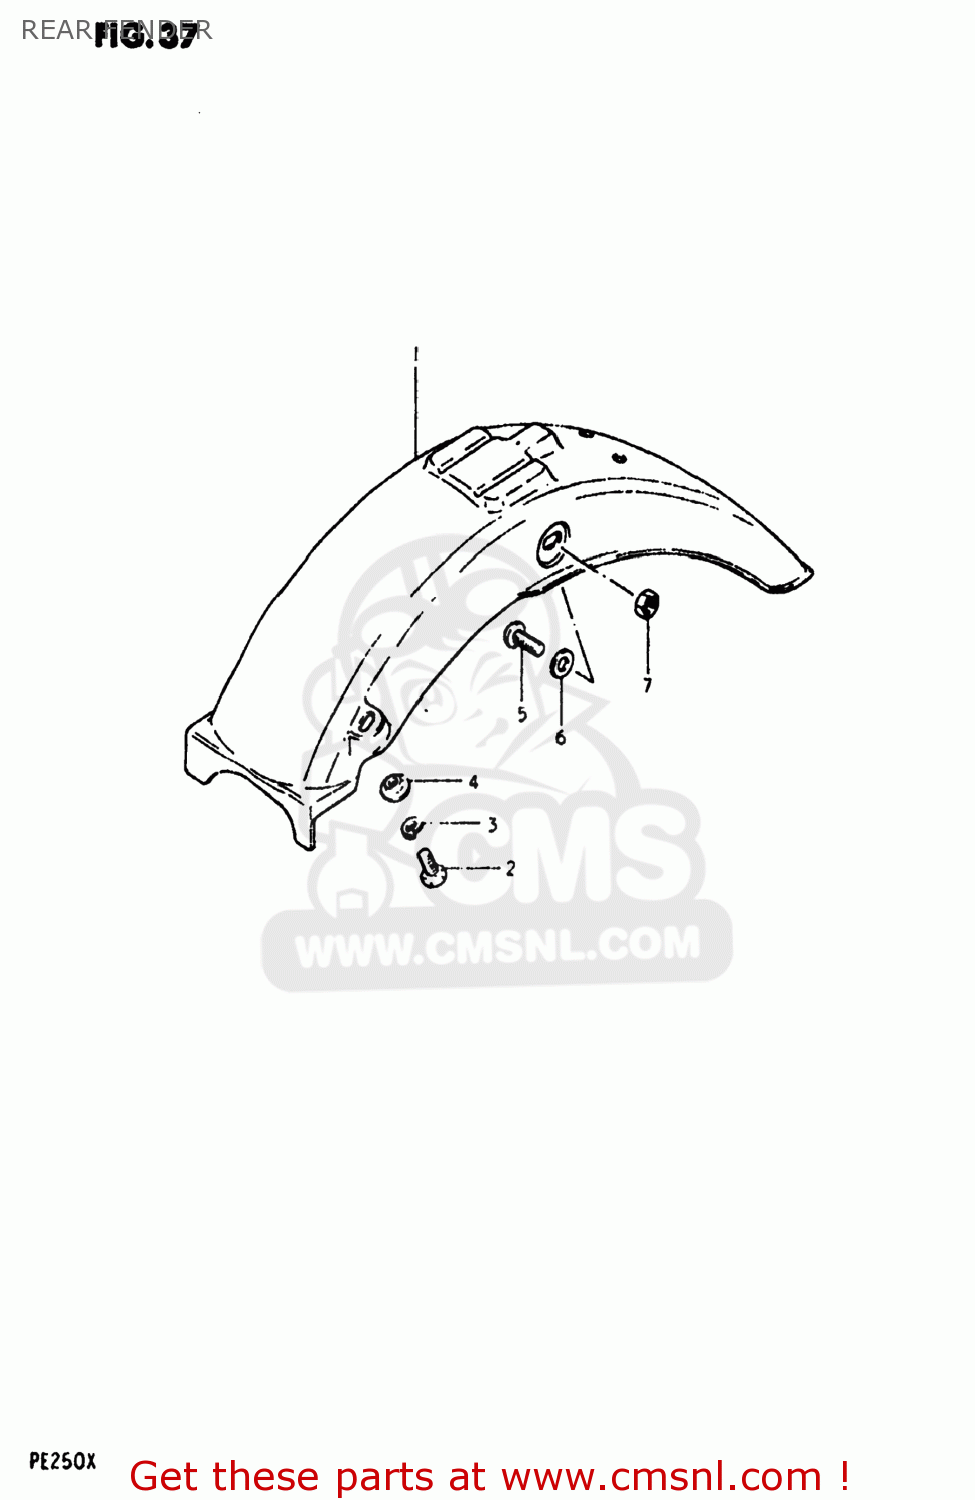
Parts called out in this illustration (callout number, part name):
1	FENDER,REAR
2	BOLT
3	LOCK WASHER
4	WASHER
5	SCREW
6	WASHER (6.5X20X1.2)
7	NUT 6MM
